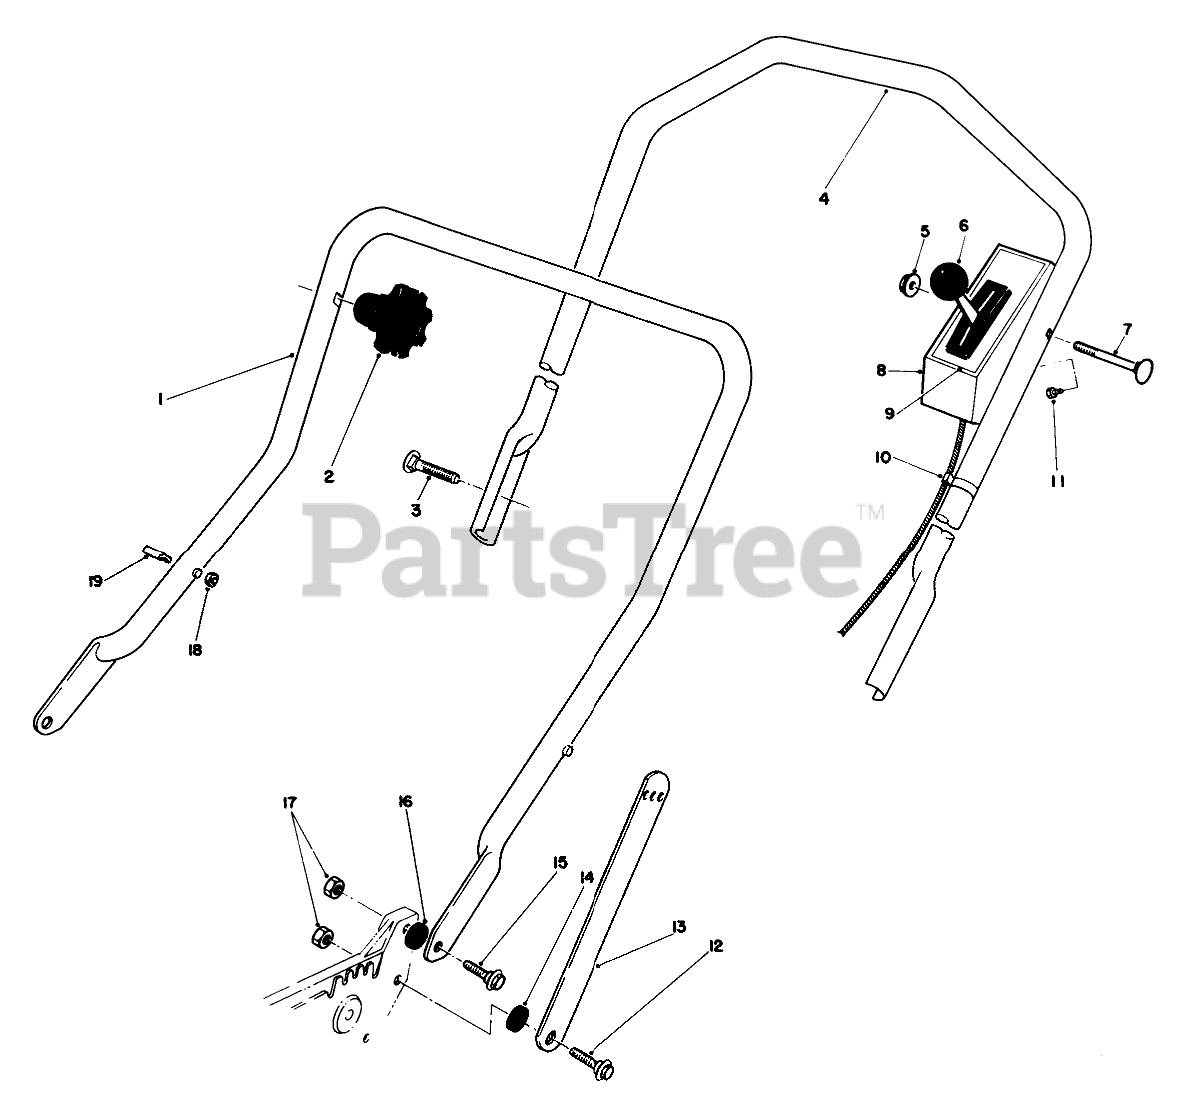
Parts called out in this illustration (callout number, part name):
1	LOWER HANDLE ASM
3	5/16-18 X 2 HNDLE SCREW
4	Handle-Upper
5	NUT-LOCK, HHF
6	Throttle-Control, Sheath lg. 49-1/2", Wire lg. 2-9/16"
7	HANDLE SCREW
8	CONTROL COVER
9	CONTROL COVER DECAL
11	SCREW-HWHTF
12	SCREW-SHOULDER
13	Handle Latch
14	SPACER
15	SCREW-SHOULDER
16	SPACER
17	NUT-LOCK, NI
18	NUT-LOCK, NI
19	HANDLE PIN
